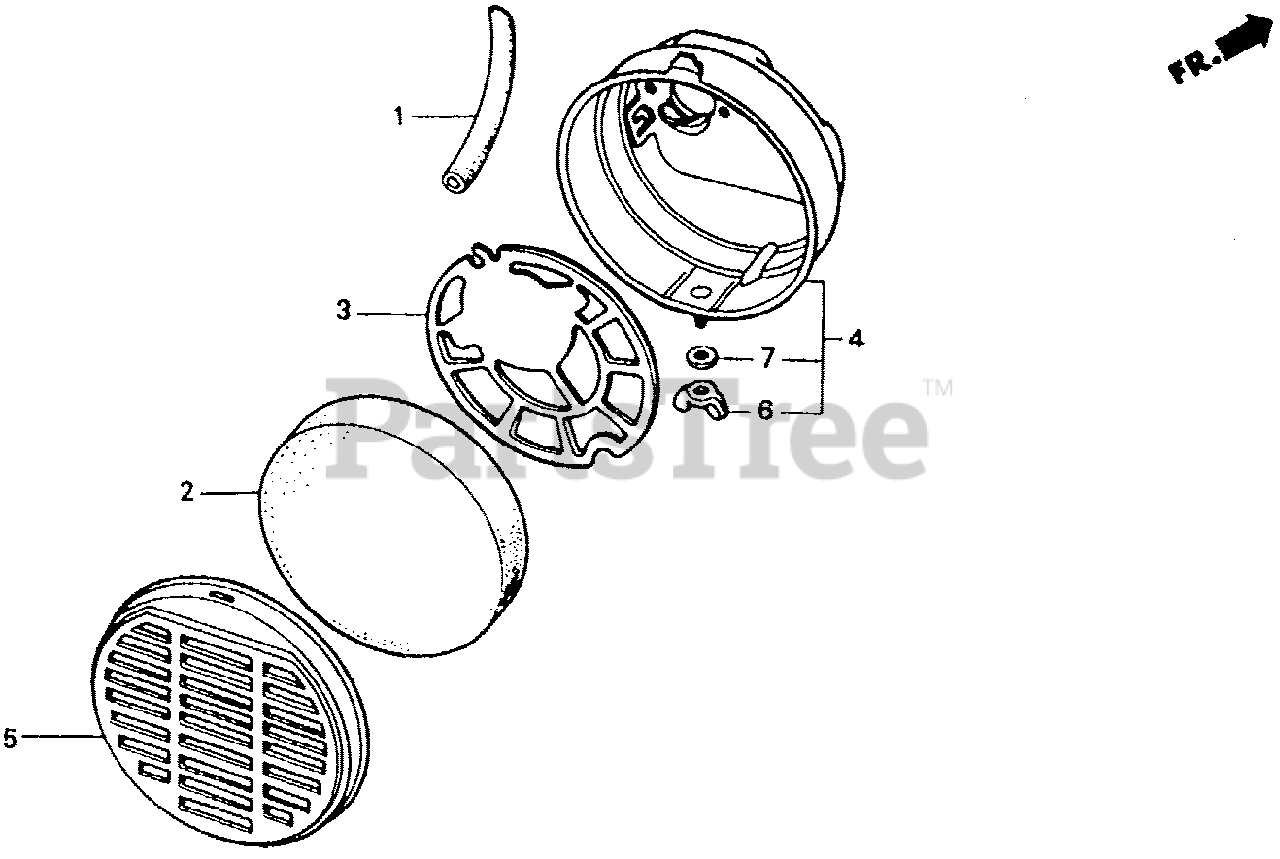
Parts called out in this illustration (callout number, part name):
1	TUBE, BREATHER
2	ELEMENT, AIR CLEANER
3	GRID, AIR CLEANER
4	HOUSING, AIR CLEANER
5	COVER, AIR CLEANER
6	WINGNUT, TOOL BOX SETTING
7	WASHER, PLAIN (6MM)
